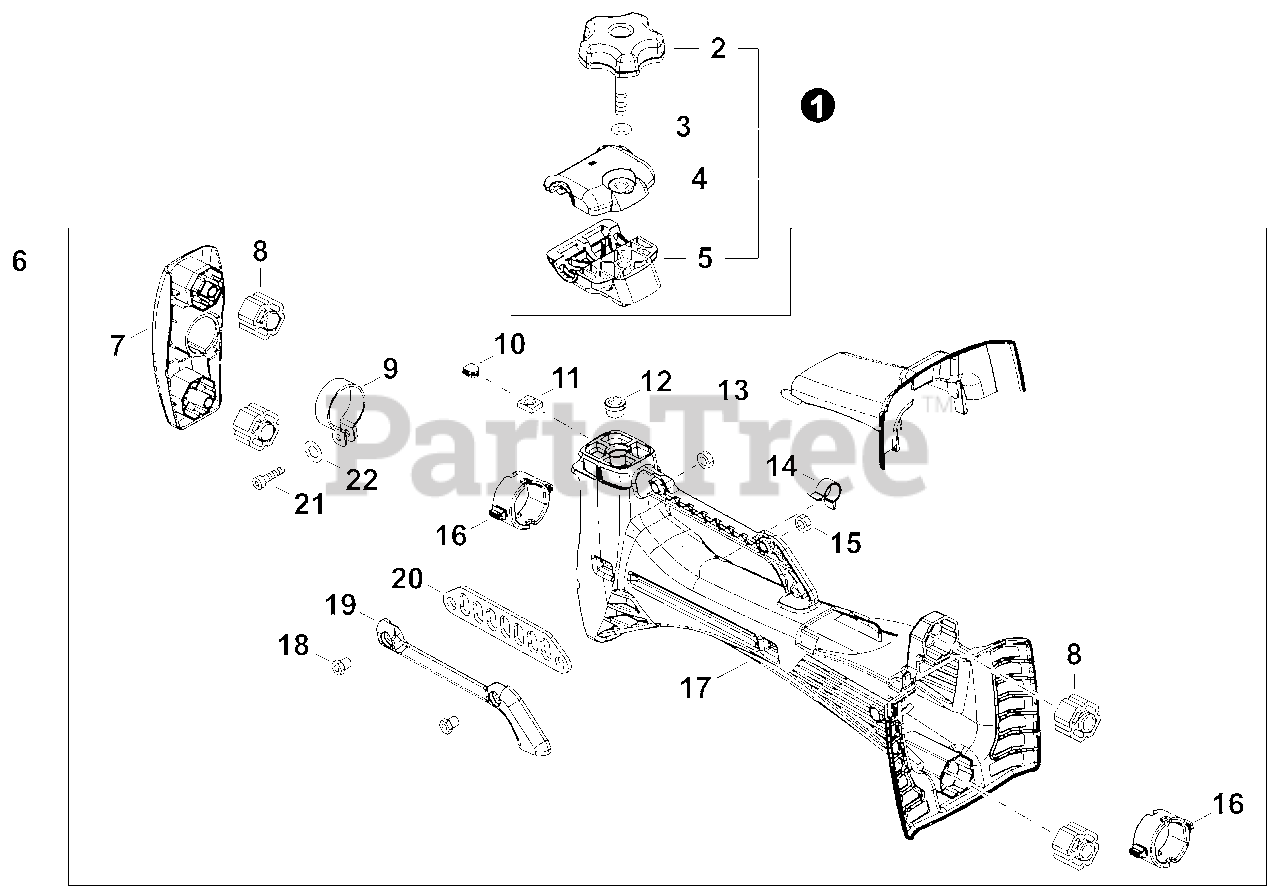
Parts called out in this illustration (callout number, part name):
1	BRACKET KIT, U-HANDLE
2	KNOB, SCREW M8
3	WASHER 8.2x17x1.6
4	BRACKET, HANDLE - UPPER
5	BRACKET, HANDLE - LOWER
6	HANDLE ASSY - SUPPORT
7	BRACKET, CUSHION
8	CUSHION
10	GROMMET, PLUG
11	NUT 8x1.25
12	COLLAR 8
13	GUIDE, CABLE
16	STOPPER, HANDLE
17	SUPPORTER, HANDLE
18	BOLT, TORX 5x16
20	PLATE, EYE
21	BOLT, TORX 6x20
22	WASHER 6.5x13x1
